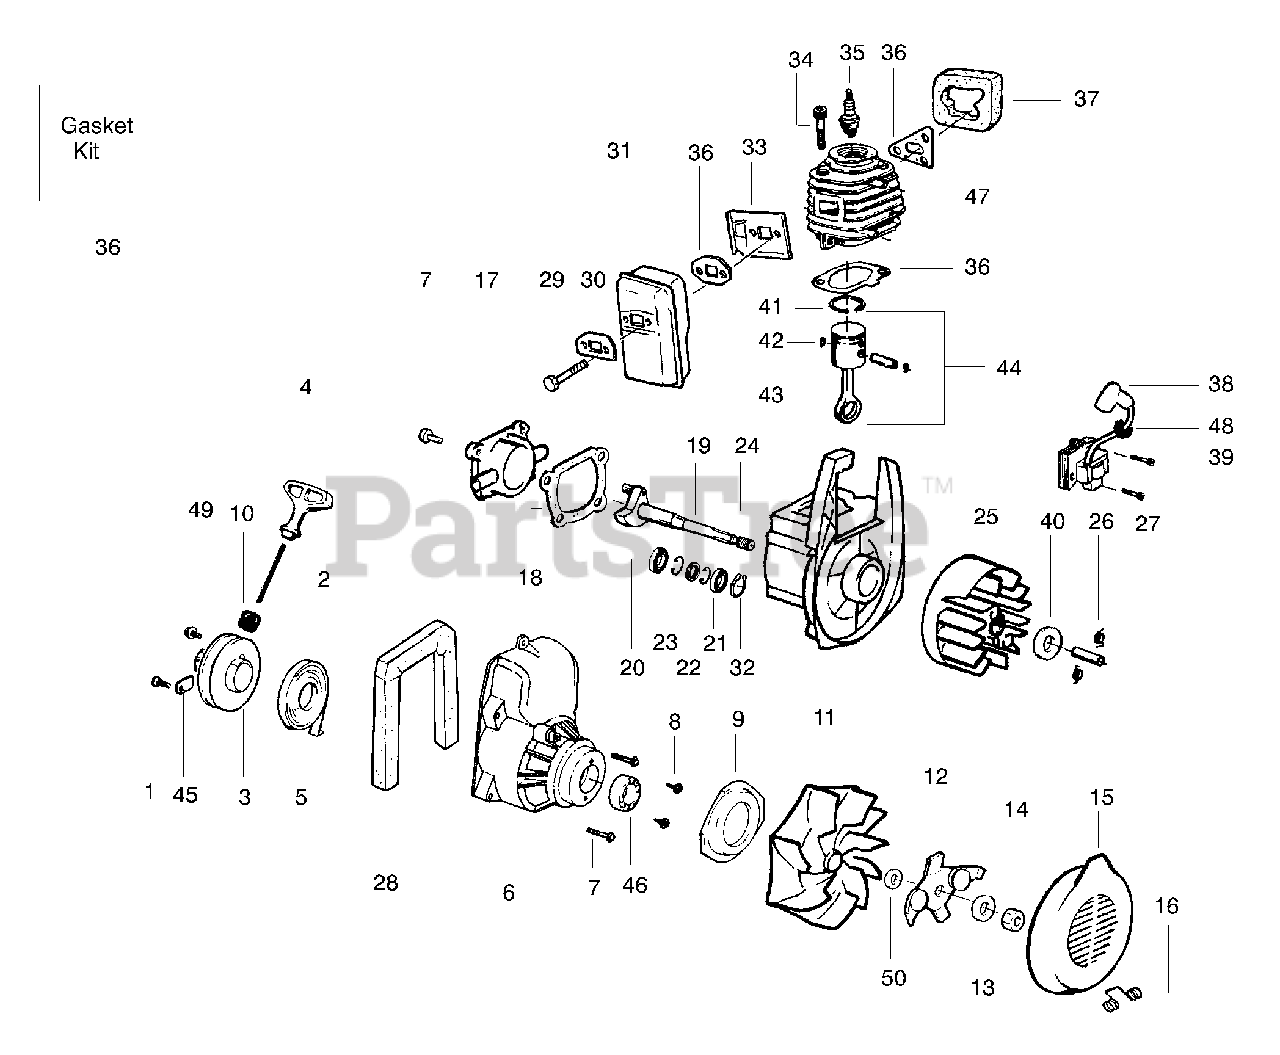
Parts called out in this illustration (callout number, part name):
2	Rope Kit
3	Starter Pulley Kit
4	Starter Handle
5	Starter Spring
6	Fan Housing w/bearing
7	Screw
11	Impeller
12	Mulch Blade Ass'y. Model 1800
13	Washer-Flat Model 1650
15	Inlet Door
16	Spring-Return Cover
17	Crankcase Cover
18	Gasket-Crankcase Shroud
19	Crankshaft Ass'y.
20	Inner Bearing
21	Outer Bearing
22	Crankcase Seal
23	Retaining Ring
24	Crankcase Ass'y.
25	Flywheel Ass'y.
26	Spring-Starter Dog
27	Flywheel Spacer
28	Foam Seal
29	Muffler Bolt
30	Muffler Cover Plate
31	Muffler Ass'y.
32	Retainer Ring-C'chaft
33	Muffler Shield
35	Spark Plug (RCJ-8Y)
36	Gasket Kit
38	Ignition Module
41	Piston Ring (2)
42	Retainer
43	Connecting Rod Ass'y.
44	Piston Kit
45	Pulley Retainer
46	Bearing
47	Cylinder
48	Grommet-Ign. Module
49	Screw-Starter Pulley
50	Washer-Belleville
